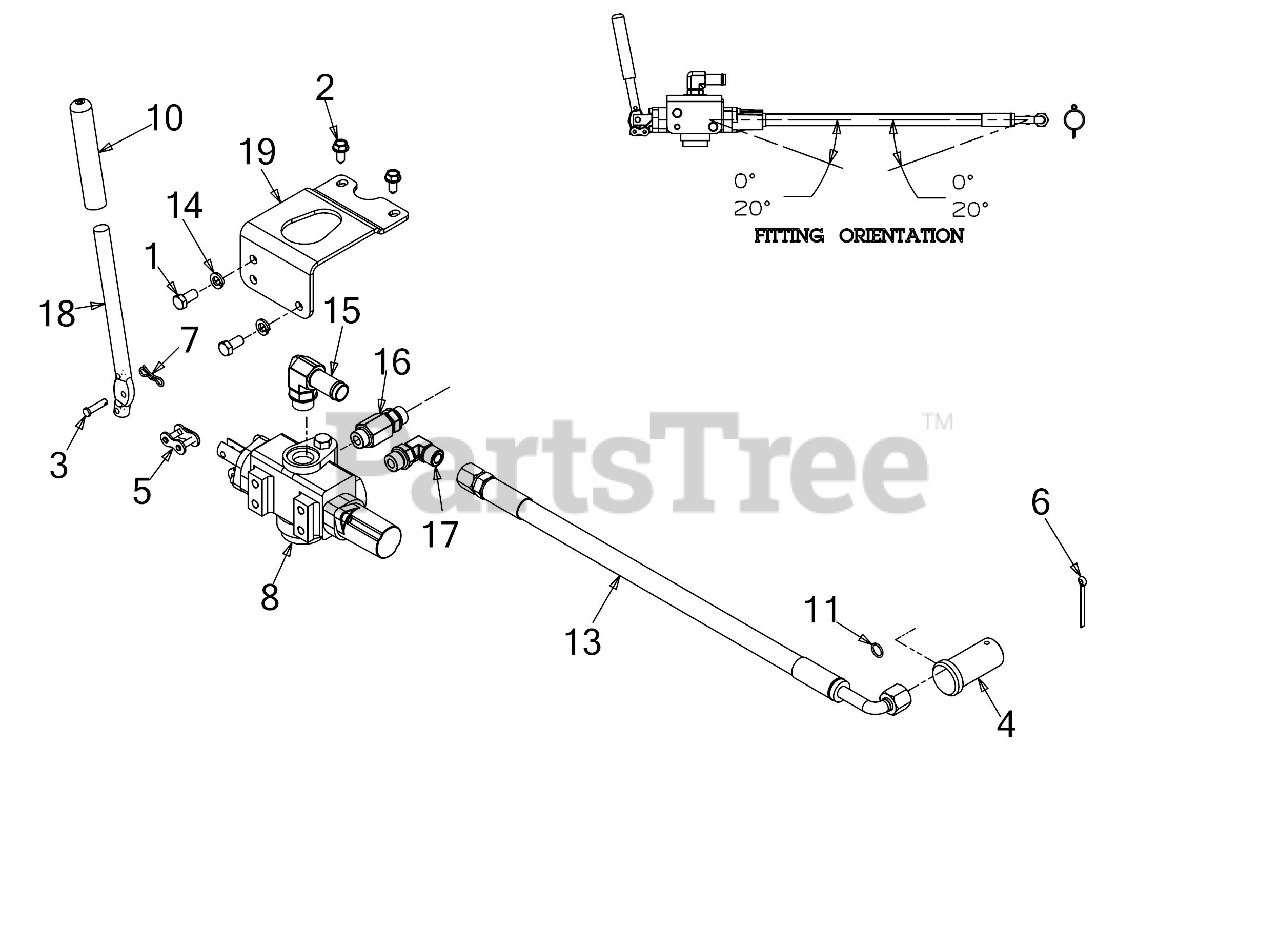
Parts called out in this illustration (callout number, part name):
1	HEX SCREW 3/8-16 x .75
2	SCREW 5/16-18 x .750
3	CLEVIS PIN .25 x 1.00
4	CYLINDER MOUNTING PIN
5	VALVE HANDLE LINK
6	COTTER PIN
7	BOW TIE COTTER PIN 1/4-5/16
8	LOGSPLITTER VALVE
11	O-RING
13	HYDRAULIC HOSE
14	LOCK WASHER 3/8
15	HYDRAULIC FITTING 7/8 ORB X .75 BEAD
16	HYDRAULIC FITTING 3/4 ORB
17	HYDRAULIC FITTING 3/4ORB X 13/16ORFS
18	CONTROL VALVE HANDLE
19	VALVE BRACKET
